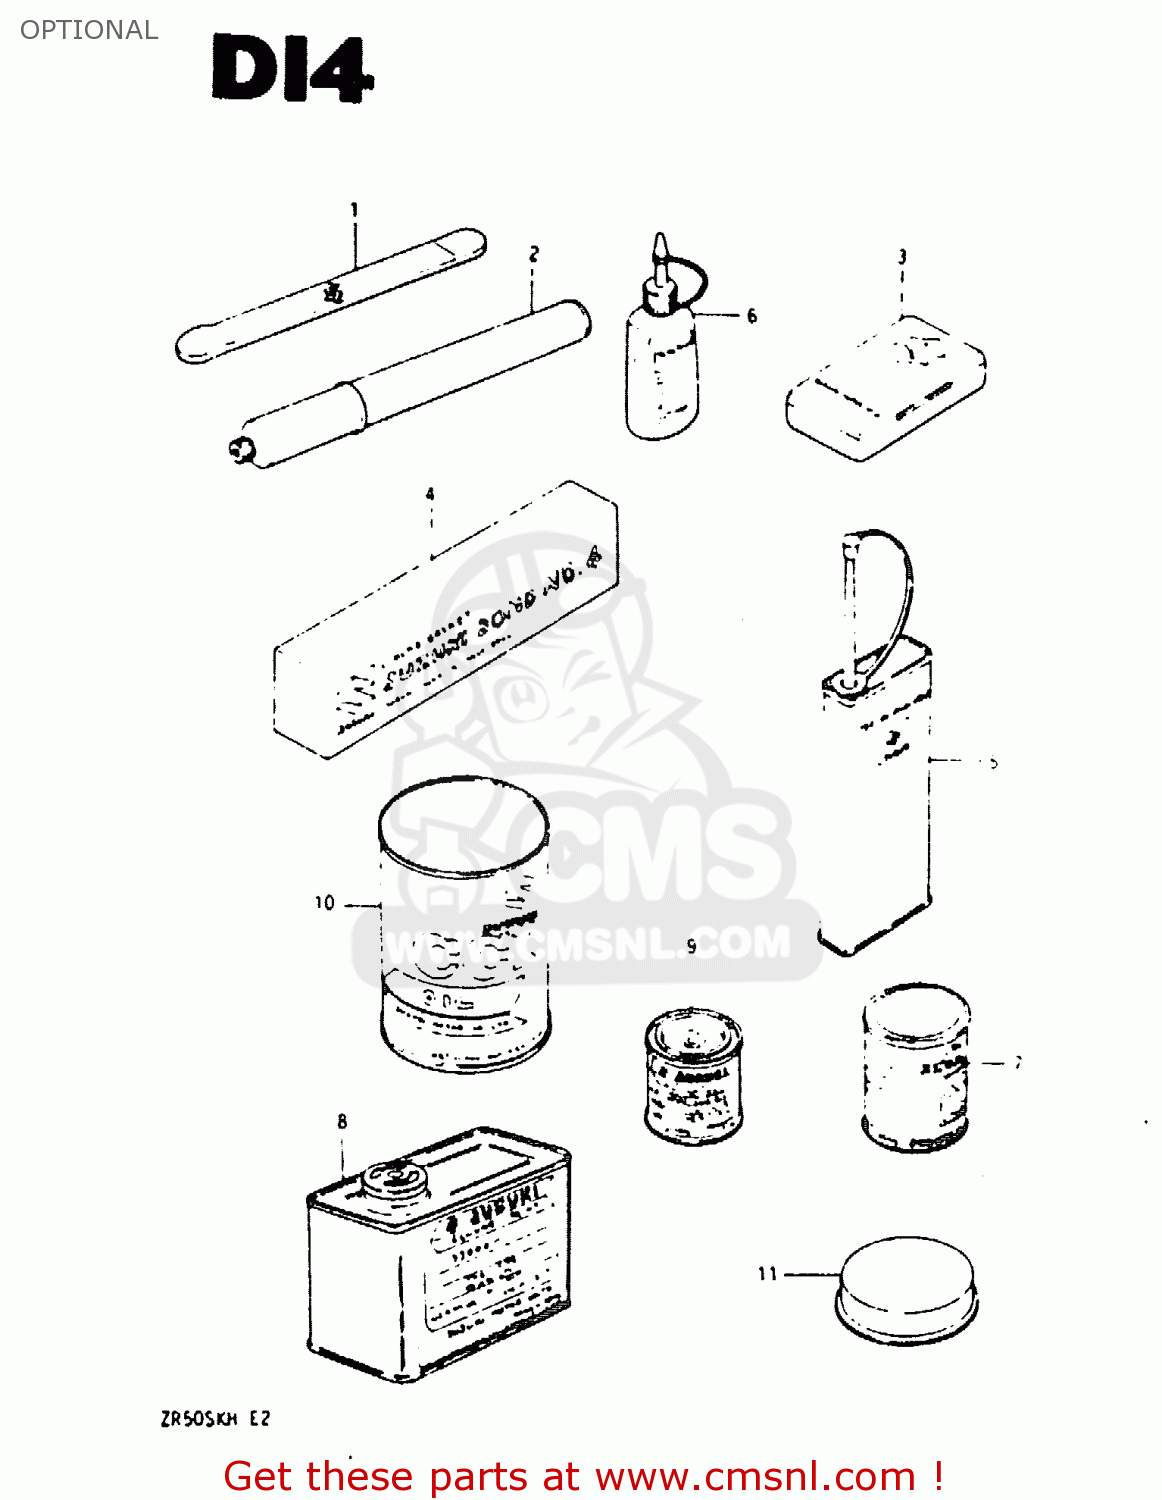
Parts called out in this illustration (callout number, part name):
1	LEVER,TIRE
2	INFLATOR, AIR
3	TUBE REPARING TOOL
4	BOND 1104
5	THREAD LOCK NO.1401 CLEAR 200G
6	THREAD LOCK NO
7	GREASE(C)EP2 LITHIUM 150G
8	PAINT (GOLD)
9	PAINT,BLACK
10	CCI OIL
11	GREASE,PBC FOR BRK PAD 20G
